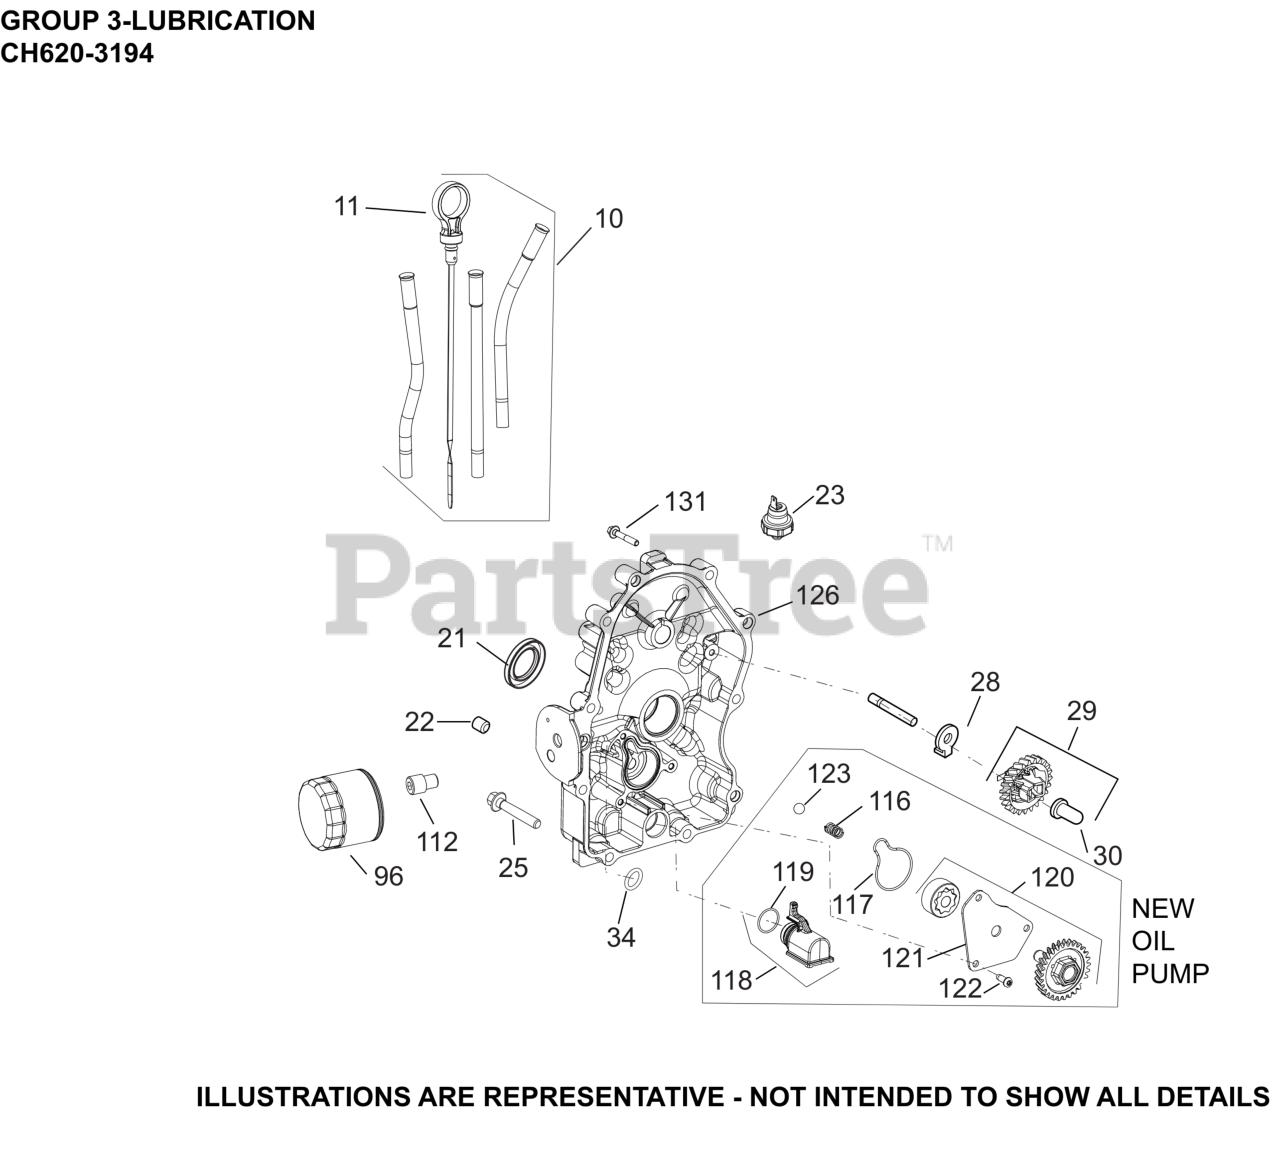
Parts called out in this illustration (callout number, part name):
10	KIT, DIPSTICK/DIPSTICK TUBES
22	PLUG, CTSK PIPE 1/8"
23	SENSOR, OIL PSI
25	SCREW, FLG M8X1.25X45
28	TAB, LOCKING
29	KIT, GOVERNOR GEAR W/PIN
30	PIN, GOVERNOR REGULATING
96	OIL FILTER
112	NIPPLE, OIL FILTER
116	SPRING, COMPRESSION
117	SEAL, OIL PUMP COVER
118	PICK-UP ASSEMBLY, OIL
119	O-RING, OIL PICK-UP
120	PUMP ASSEMBLY, OIL
121	COVER, OIL PUMP
122	SCREW, BUTTON HEAD
123	PRESSURE RELIEF BALL
126	KIT, CLOSURE PLATE ASSY
131	SCREW, HEX FLANGE
NI	SHAFT, GOVERNOR GEAR
